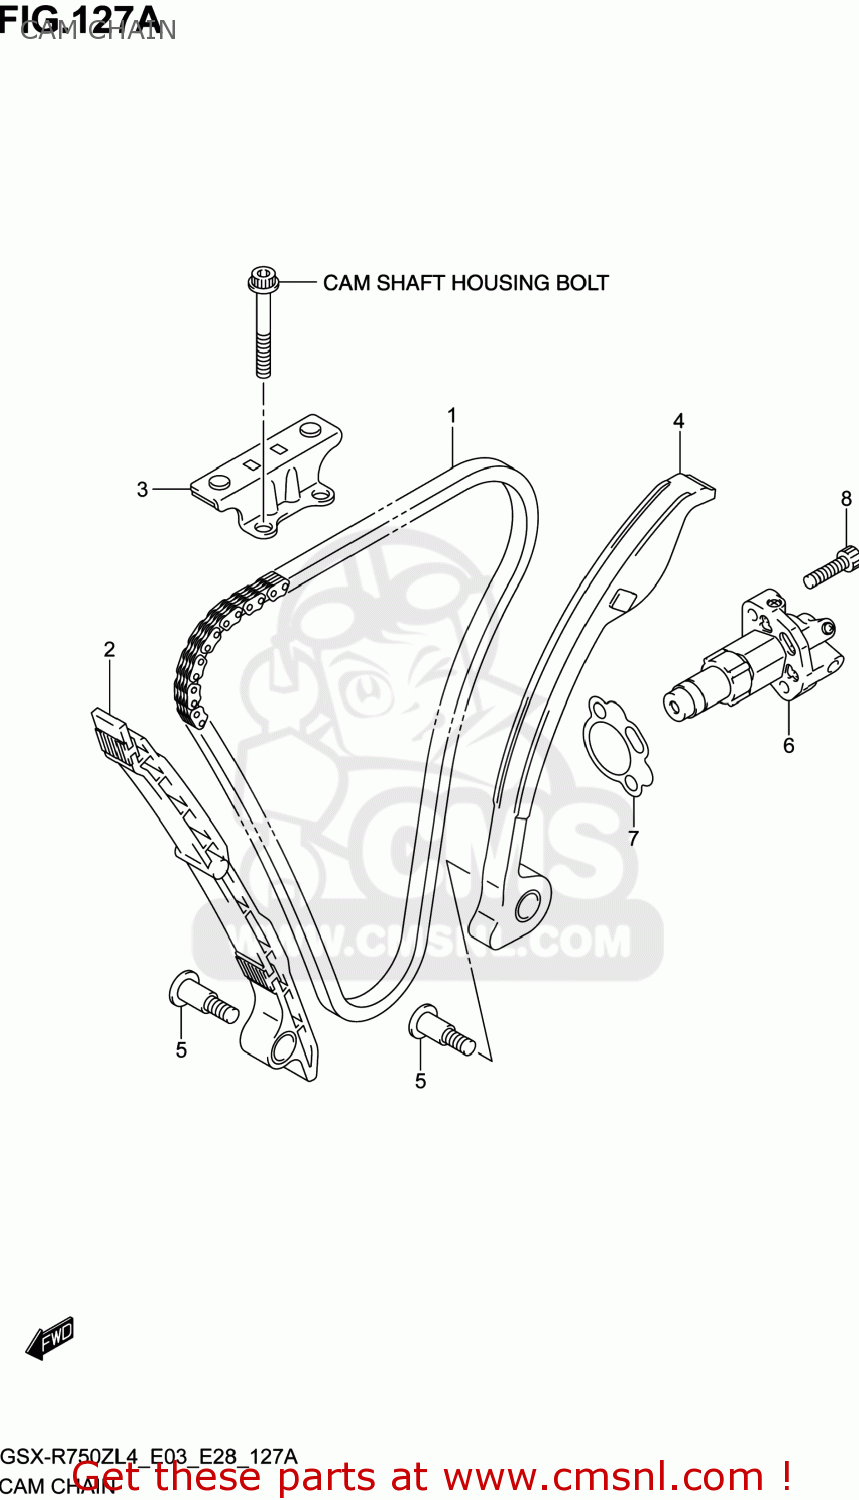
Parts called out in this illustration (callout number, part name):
1	CHAIN,CAMSHAFT DRIVE
2	GUIDE,CAM CHAIN NO.1
3	GUIDE,CAM CHAIN NO.2
4	TENSIONER,CAM CHAIN
5	BOLT,CAM CHAIN TENSIONER
6	ADJUSTER ASSY,TENSIONER
7	GASKET,TENSIONER ADJUSTER (NAS)
8	BOLT
